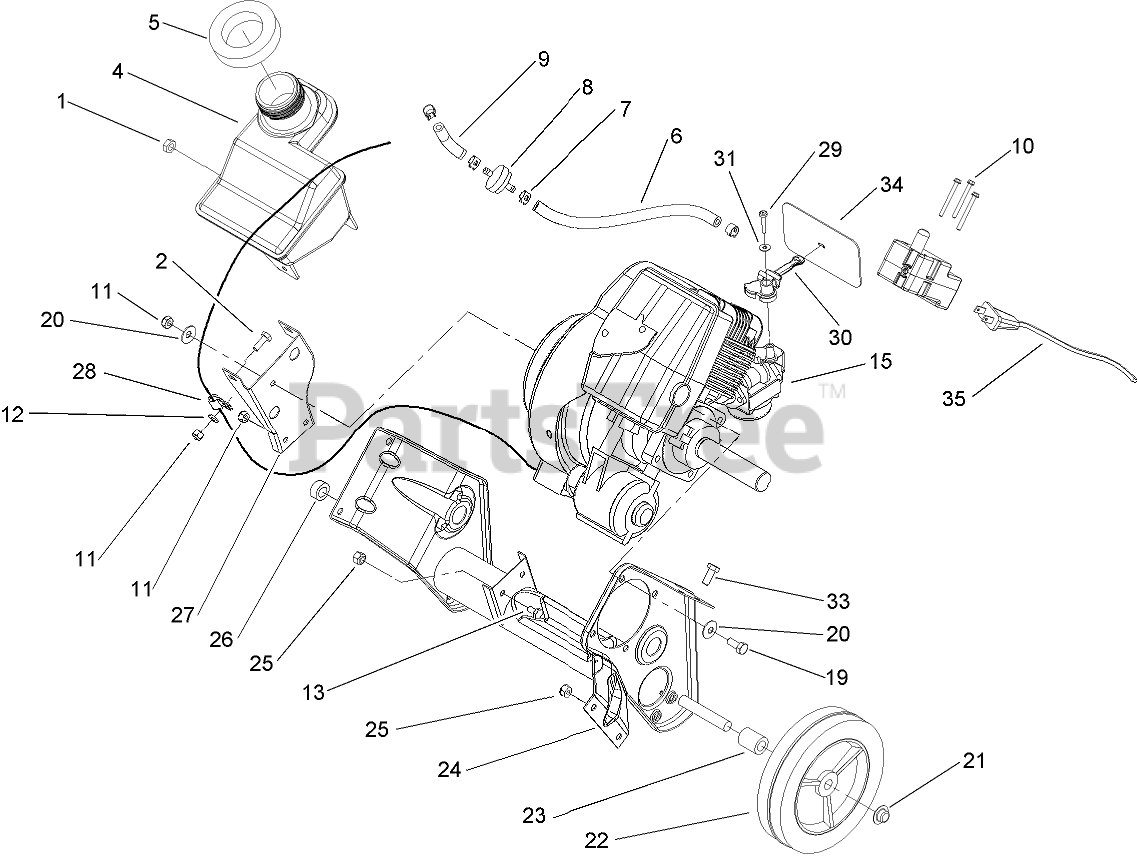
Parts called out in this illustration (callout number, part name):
1	NUT-LOCK, CONE
2	SCREW-HH
4	Tank-Gas
5	SEAL-FOAM
6	LINE-FUEL
7	CLAMP-HOSE
8	FILTER-FUEL
9	HOSE-FUEL
10	SCREW-PLASTITE
11	NUT-LOCK, NI
12	WASHER-FLAT
13	SCREW-HH
19	SCREW-HH
20	WASHER-BELLEVILLE
21	NUT-PUSH
22	WHEEL
23	SPACER-WHEEL
25	NUT-LOCK, NI
26	SPACER-WHEEL
27	BRACKET-SUPPORT, RECOIL
28	CLAMP
29	SCREW-PPH, PLASTITE
30	LEVER-CHOKE
31	WASHER-FLAT
33	SCREW-HH
34	SHIELD-HOLE, CHOKE
35	CORD-ELECTRIC
